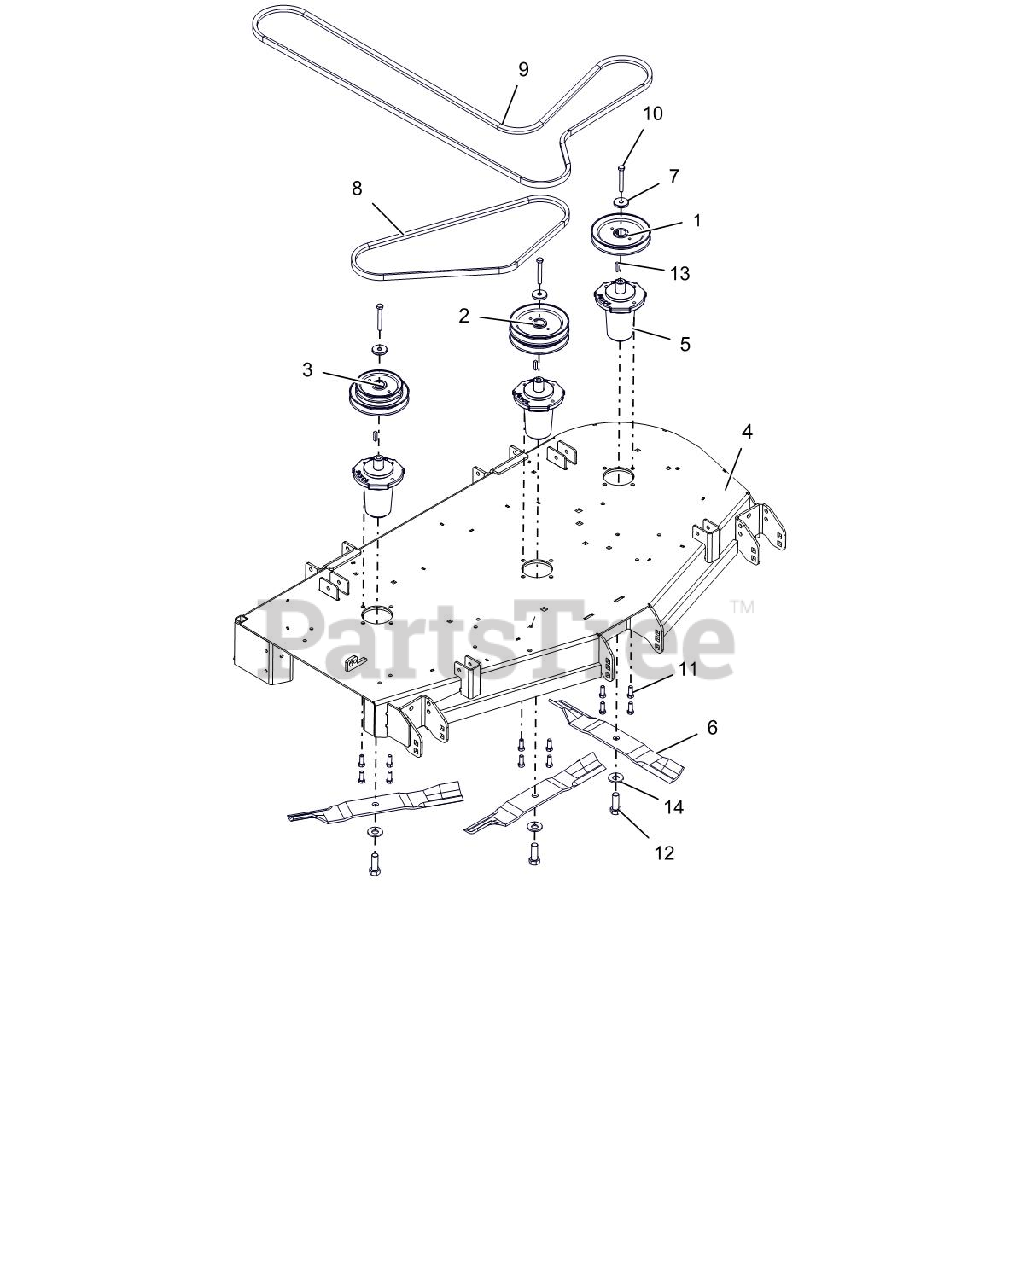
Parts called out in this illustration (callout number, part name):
1	PULLEY, SINGLE-1"ID X 6" OD
2	PULLEY, DOUBLE
3	PULLEY, DBL-1"IDX6.00"&4.75"OD
4	52"SIDE DISCH DECK WMT W/SAFE
5	ASM, MAINT FREE SPINDLE
6	BLADE, 18.00" MOWER (HI-LIFT)
7	RETAINER, SHEAVE
8	V-BELT, B-COGGED
9	V-BELT, HB RAW EDGE EPDM
10	BLT-HEX .38-16X2.75 GR8 YWZC
11	BLT-HEX .38-16X1.0 GR8 YZ EP30
12	BLT-HEX .62-18X1.75 GR8 YWZC
13	KEY, SQ .25X.25X1.00 RC 40-50
14	WSHR-BLVL .669X1.535X.138
